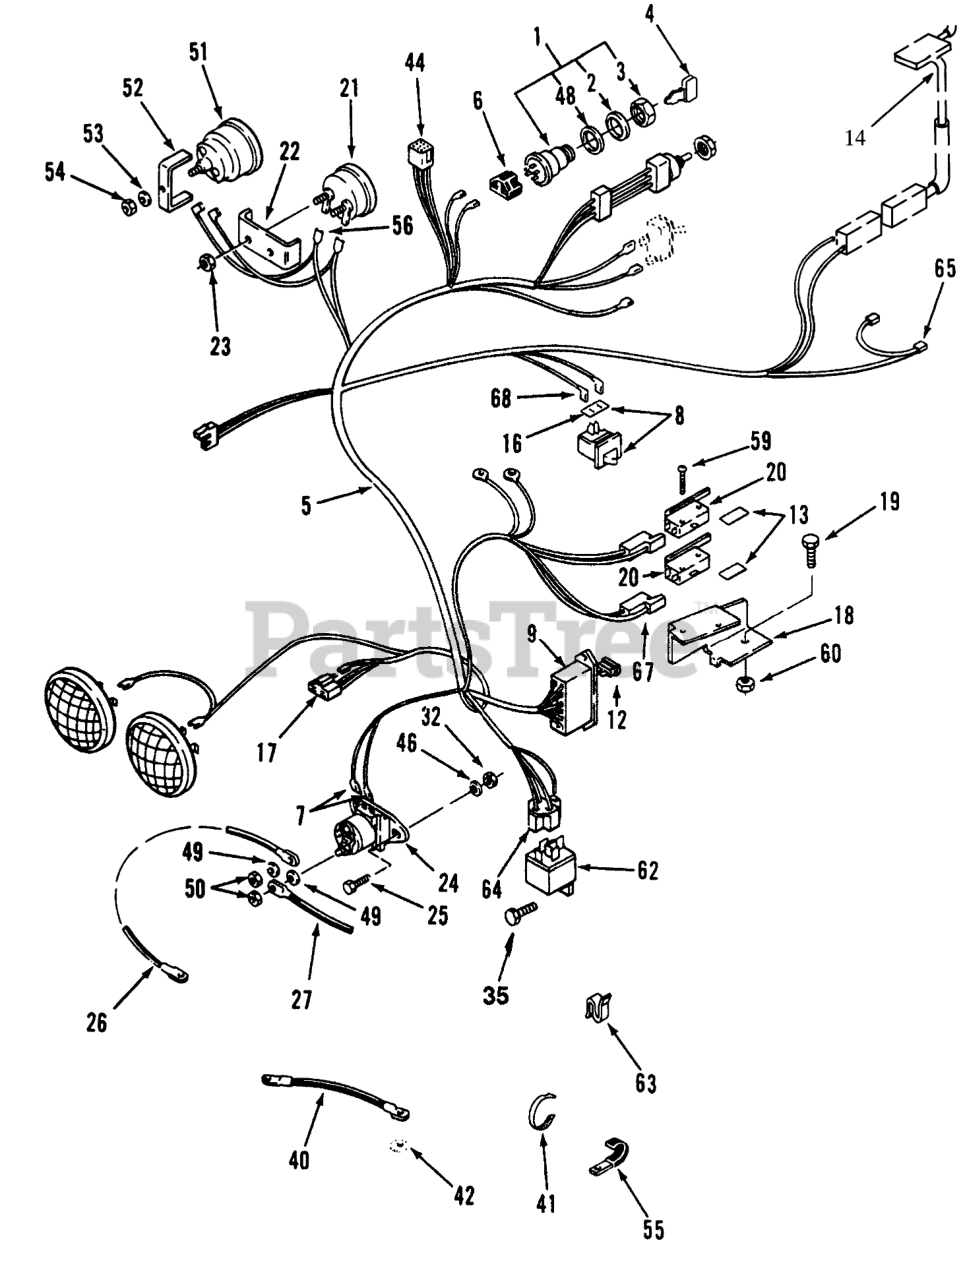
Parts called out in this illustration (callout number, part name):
1	KEY SWITCH ASM
2	LOCKWASHER
4	KEY-IGNITION
5	Harness Assy-Wiring (Incl. Ref. #6, 7, 9, 44 & 64-68)
6	CONNECTOR BODY ELECT
7	TERMINAL 10
8	Switch-Clutch Interlock, (Incl. Ref. #16)
9	FUSE-HOLDER 4 WAY
12	FUSE-BLADE, 15 AMP
13	BARRIER - SWITCH
14	SWITCH-SEAT
16	SHIELD-DIRT SPST
17	5-CONTACT CONN BODY
18	BRACKET-SWITCH
19	Bolt
20	SWITCH
21	VOLTMETER
22	CLAMP-MOUNTING
23	HEX NUT 10-32 E.S.
24	Solenoid
25	Screw
26	ASSY WIRE
27	CABLE-BLACK
32	Nut
40	WIRE GROUND
41	PLASTIC TIE
42	WASHER-LOCK, INTERNAL
44	Terminal
48	Washer
49	WASHER-LOCK
50	NUT-JAM
51	Meter-Hour (Incl. Ref.# 52-54)
52	BRKT-GAUGE MOUNTING
53	Lockwasher
54	Hex Nut
55	CLIP
59	Screw
60	NUT HEX 4-40 ELAST
62	RELAY
63	CLIP-CABLE
64	TERMINAL 10
65	Sur-Plug
68	Terminal
